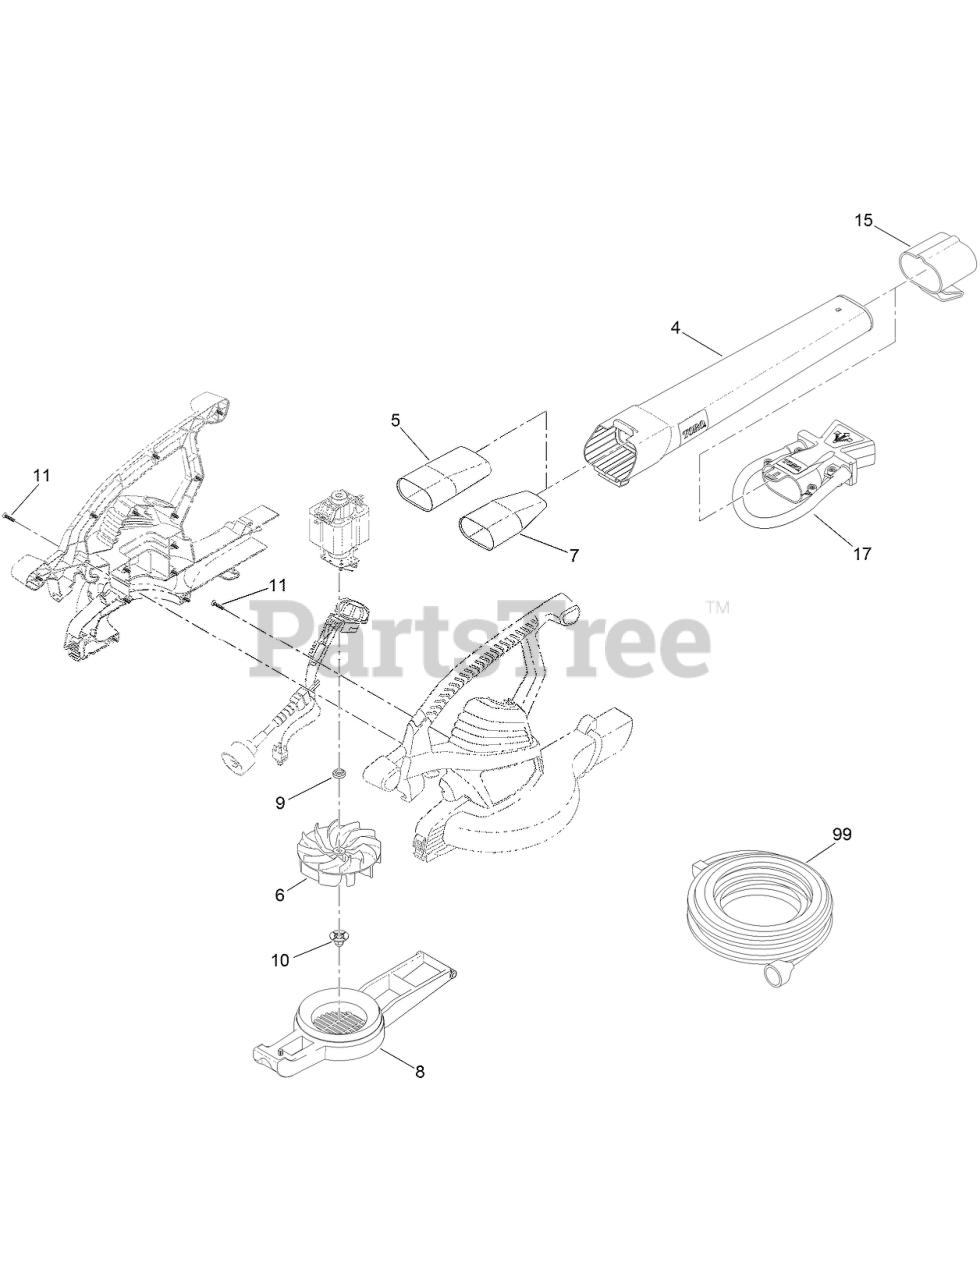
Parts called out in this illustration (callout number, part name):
4	TUBE-BLOWER
5	TUBE-INSERT
6	IMPELLER ASM
7	INSERT-TUBE, MPH
8	COVER-INLET
9	BUSHING-MOTOR
10	NUT-IMPELLER
11	SCREW-PPH
15	ADAPTER-WRAP, CORD
17	OSCILLATOR NOZZLE ASM
99	EXTENSION CABLE (12M)
